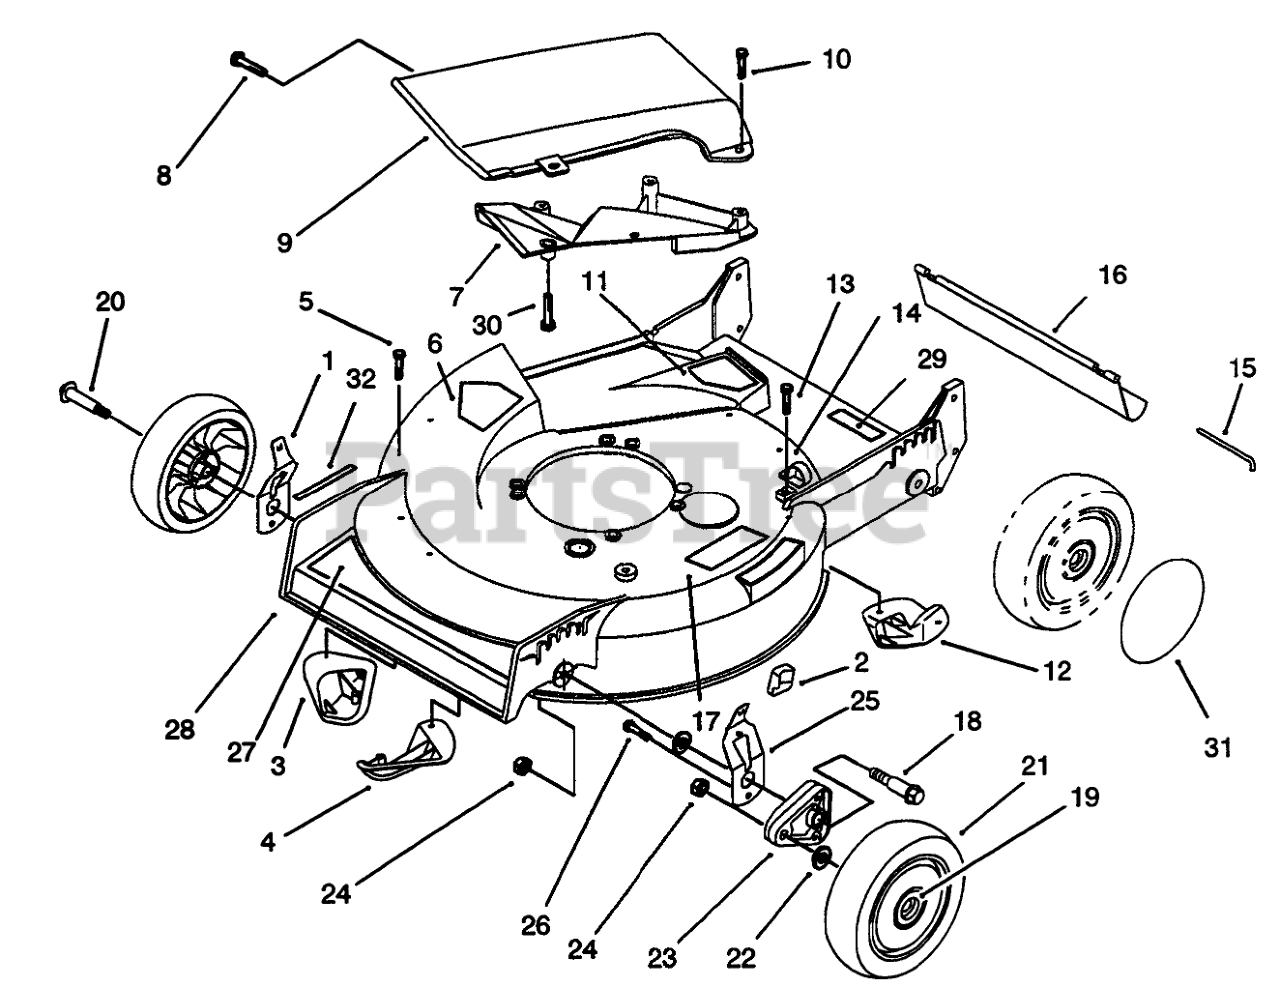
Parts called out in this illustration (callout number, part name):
1	RH SPRING ARM ASSEMBLY
2	KNOB-ARM
3	KICKER-FRONT
4	KICKER-RH
5	SCREW-PPH
6	DECAL-DANGER
7	Deflector-Recycler
8	SCREW AND WASHER ASM
9	Cover Assembly (Incl. Ref #7 & 19)
10	SCREW-HWH
11	DECAL - DANGER
12	KICKER-REAR
13	SCREW-HWHTF
14	CLAMP-R
15	ROD-SHIELD
16	SHIELD-TRAILING
17	DECAL-INSTRUCTION, SAFETY
18	BOLT-SHOULDER
19	BUSHING
20	BOLT-WHEEL
21	Wheel & Tire Assembly (Incl. Ref. #19)
22	WASHER
23	ARM-PIVOT, FRONT
24	NUT-LOCK
25	LH SPRING ARM ASSEMBLY
26	SCREW-HWH
27	DECAL - DECK
28	Housing Assembly (Incl.Ref.#3-6,11,12,117,29,&31)
29	DECAL-WARNING
30	Screw-Pan Hd.
31	WHEEL COVER
32	DECAL - HOC
